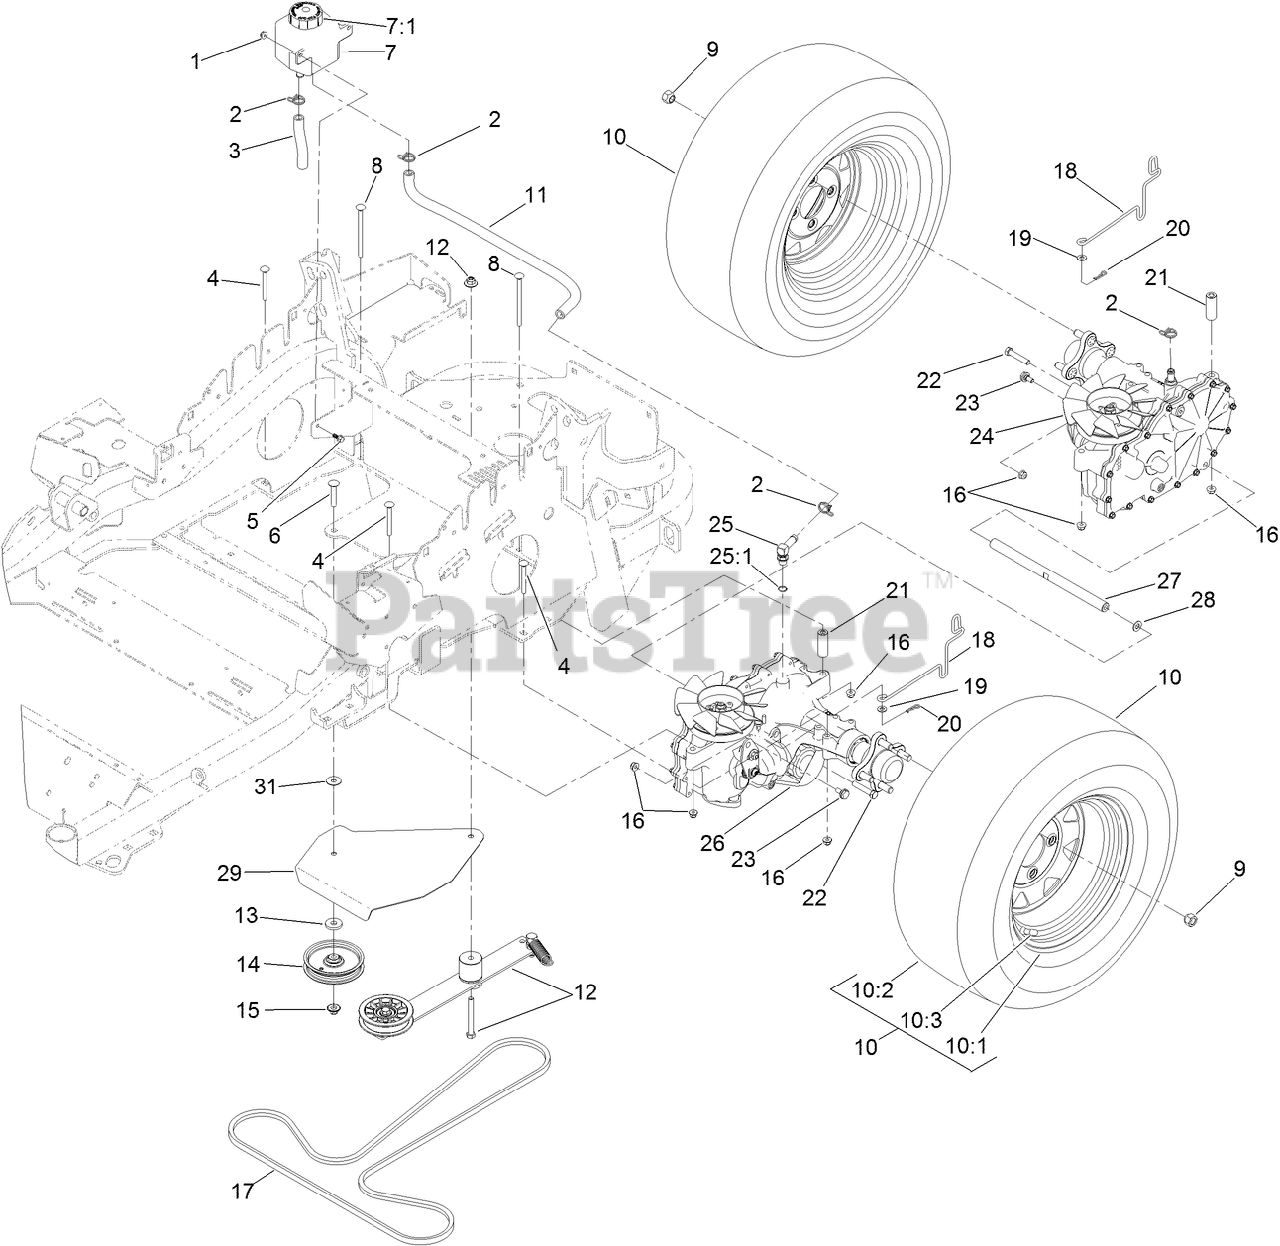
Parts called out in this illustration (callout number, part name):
1	NUT-HF
2	CLAMP-HOSE
3	HOSE-HYD
4	SCREW-CARR
5	SCREW-HHF
6	BOLT-CARRIAGE
7	TANK-HYD
7:1	CAP-RESERVOIR, HYD
8	SCREW-CARR
9	NUT-LUG
10	WHEEL AND TIRE ASM
10:2	TIRE
10:3	STEM-VALVE
11	HOSE-HYD
12	HYDRO IDLER ARM ASM
13	WASHER
14	PULLEY-IDLER
15	NUT-FLANGE, NI
16	NUT-HF, NI
17	BELT-V
18	ROD-BYPASS
19	WASHER-PLAIN
20	PIN-COTTER
21	SPACER-HYDRO
22	SCREW-HH W/LOCTITE
23	BOLT-SHOULDER
24	RH TRANSAXLE ASM
25	FITTING-ELBOW, 90
25:1	O-RING
26	LH TRANSAXLE ASM
27	SHAFT-CROSS, HYDRO
28	WASHER-FLAT
29	PLATE-GUARD
31	WASHER
